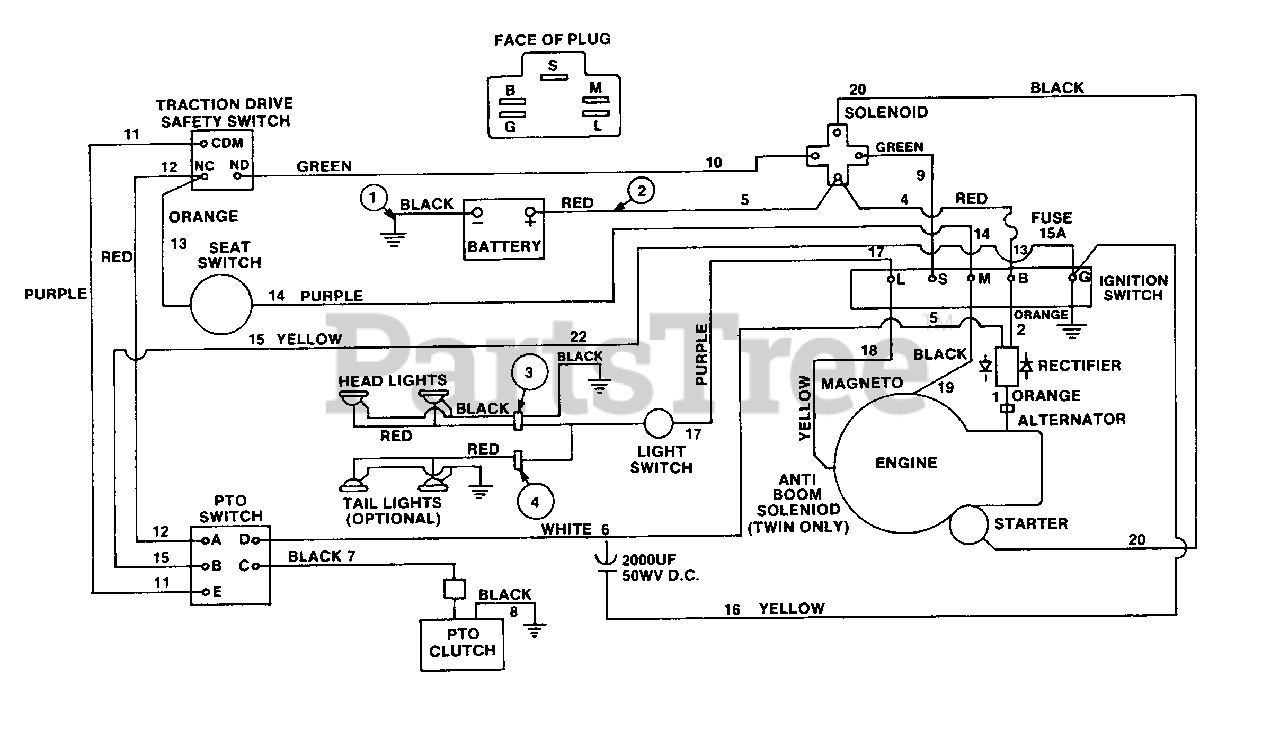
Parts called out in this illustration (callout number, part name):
1	CABLE- Battery to Ground
2	HARNESS- Main
3	HARNESS- Head lights
4	HARNESS- Tail lights
